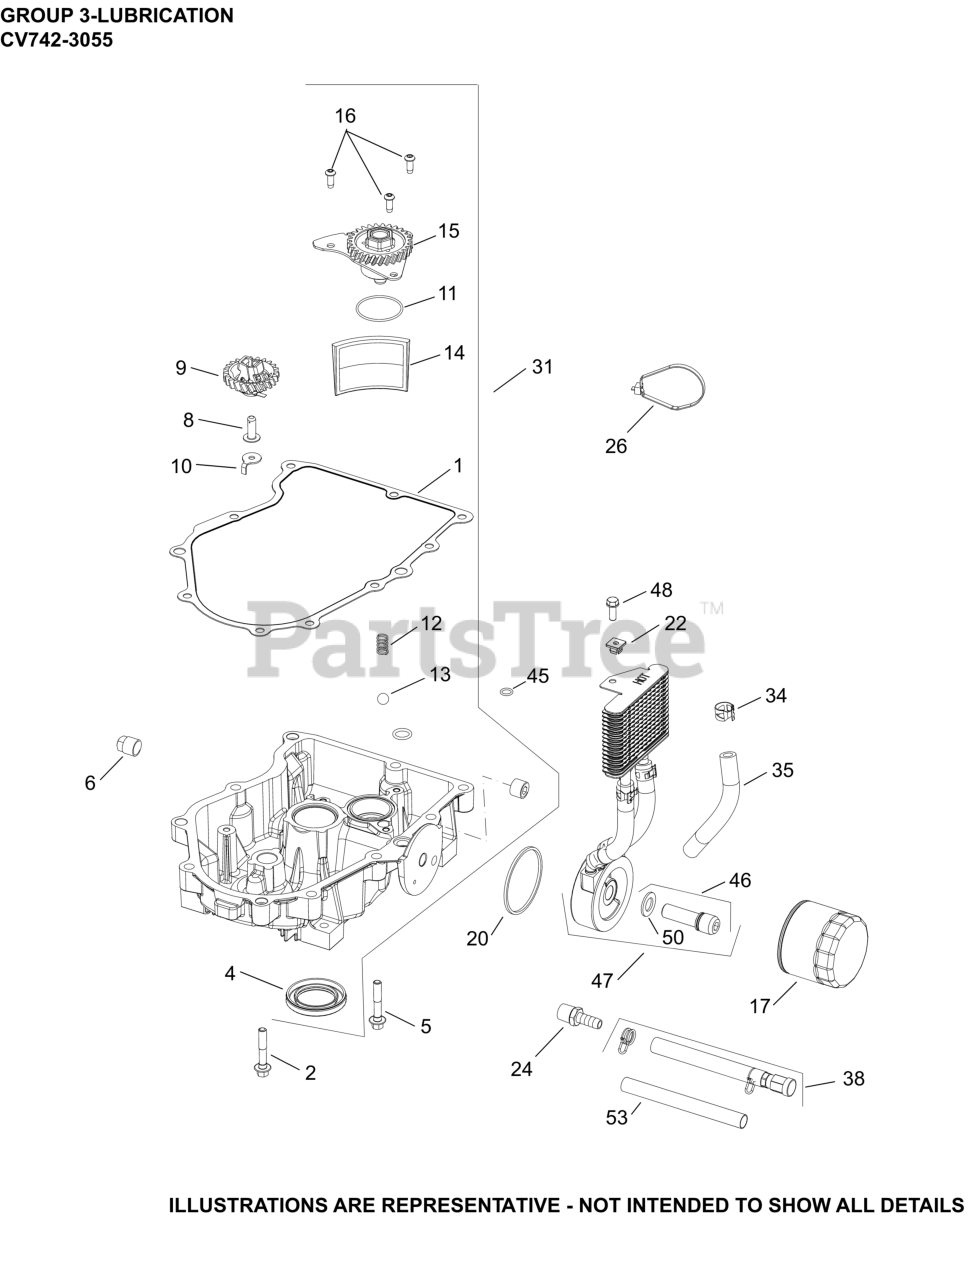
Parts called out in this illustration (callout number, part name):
1	KIT, OIL PAN GASKET
1	GASKET, OIL PAN
2	SCREW, FLG M8X1.25X45
5	SCREW, HEX FLANGE
6	PLUG, SQ HD PIPE 3/8"
7	SHAFT, GOVERNOR GEAR
8	PIN, GOVERNOR REGULATING
9	KIT, GOVERNOR GEAR W/PIN
10	TAB, LOCKING
11	O-RING (1.78" DIA)
12	SPRING, COMPRESSION
13	PRESSURE RELIEF BALL
14	SCREEN, OIL
15	PUMP, OIL ASSEMBLY
16	SCREW, BUTTON HEAD
17	OIL FILTER
17	FILTER, OIL EXTENDED LIFE
20	O-RING, OIL COOLER
22	NUT, PLASTIC - BLACK
24	FITTING, BARBED
31	PAN, ASSEMBLY OIL (SERVICE)
31	KIT, OIL PAN ASSEMBLY
34	CLAMP, HOSE LOW PROFILE
35	KIT, HOSE 140MM
38	HOSE, OIL ASSEMBLY
45	O-RING (.5" DIA)
46	KIT, OIL FILTER NIPPLE
47	KIT, OIL COOLER
48	SCREW, HEX HEAD
50	WASHER, FLAT
52	SHAFT, GOVERNOR GEAR
53	SLEEVE, ANTI ABRASION
NI	FITTING, BARBED (3/8 NPTF, MALE, PATCH)
